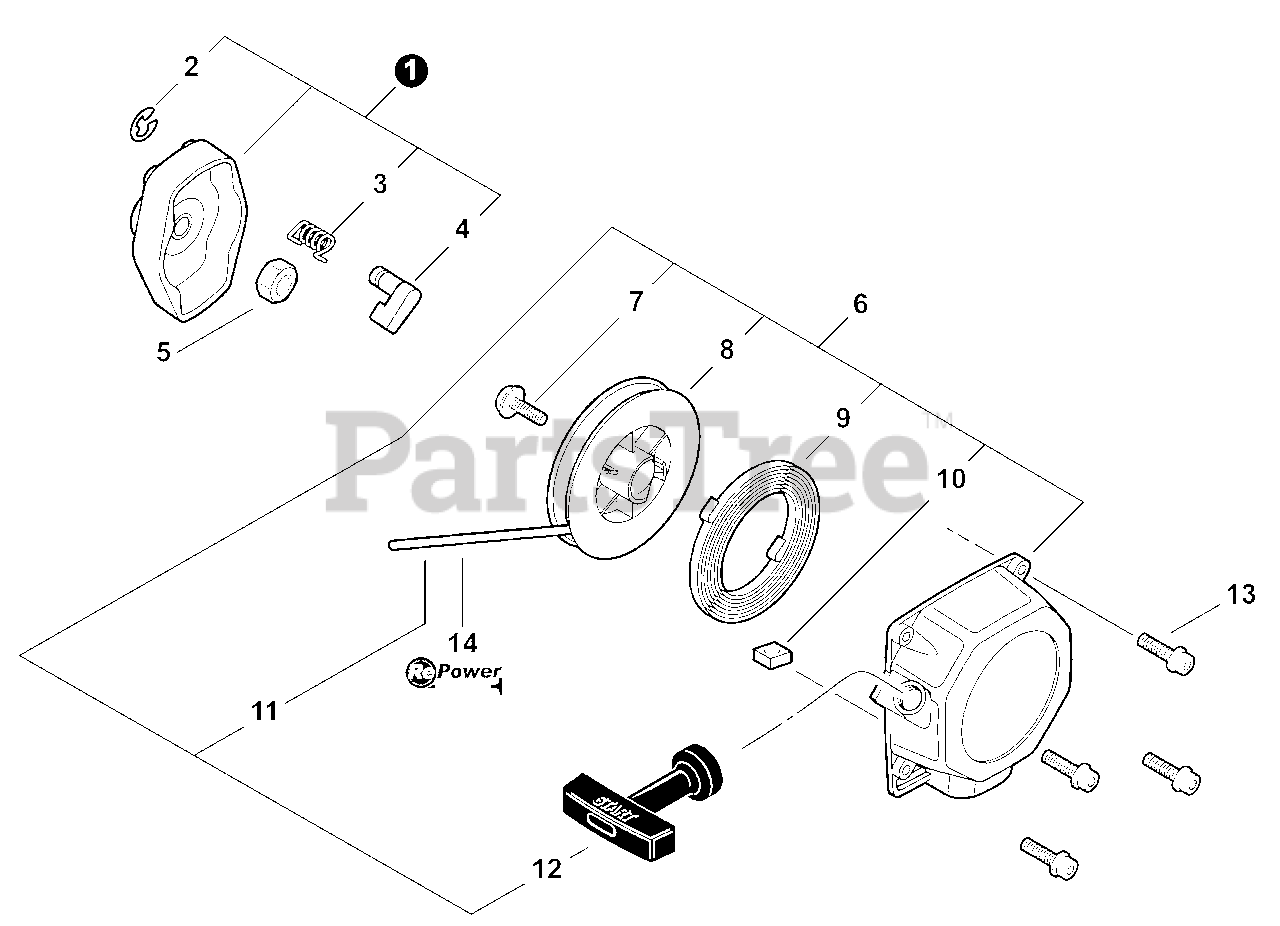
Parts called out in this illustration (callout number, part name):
1	STARTER PAWL ASY
2	RING, RETAINING - 4
3	SPRING, RETURN
4	PAWL, STARTER
6	STARTER ASY
8	REEL, ROPE
9	SPRING, REWIND
10	NUT
11	ROPE, STARTER - 3.5×900
12	GRIP, STARTER
13	SCREW - 5×16
14	ROPE, STARTER - REPOWER BULK
